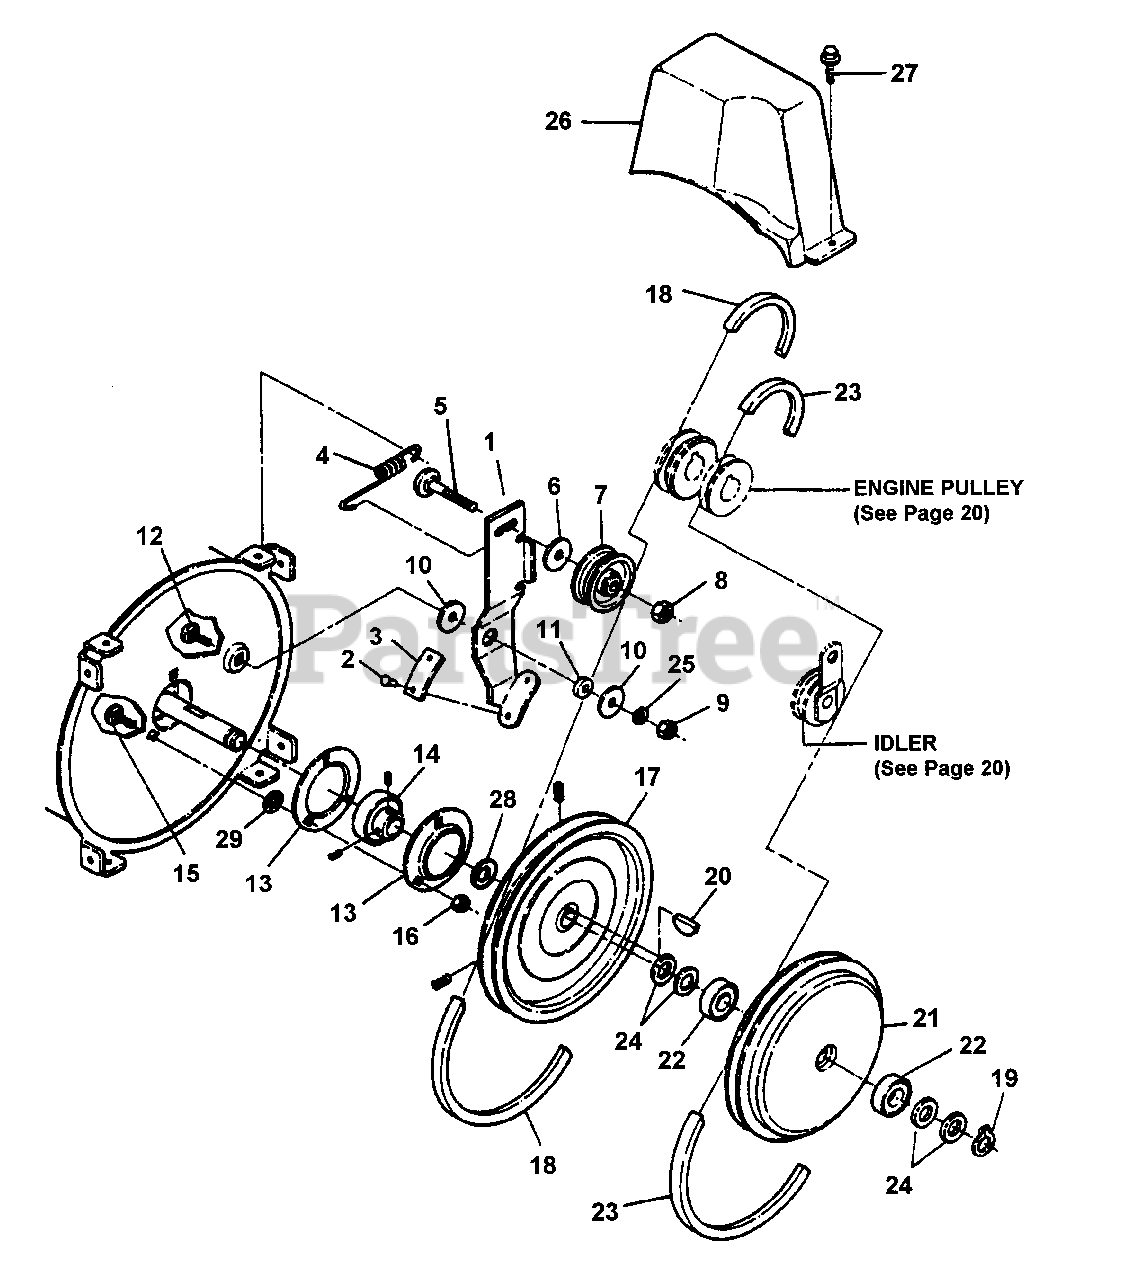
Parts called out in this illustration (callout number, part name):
1	ASSEMBLY, Idler Arm
2	RIVET
3	PAD, Brake
4	SPRING
5	BOLT, 3/8-16 x 1-1/2" Square Neck Carriage, Grade 2
6	WASHER, 3/8" Flat
7	PULLEY, Idler
8	NUT, 3/8-16 Hex Top Lock
9	NUT, 5/16-18 Hex, Grade B or 5
10	WASHER, 5/16 x 1-1/4" Flat
11	SPACER
12	BOLT, 5/16-18 x 1" Square Neck Carriage, Grade 5
13	HOUSING, Bearing
14	BEARING
15	BOLT, 5/16-18 x 3/4" Short Neck Carriage, Grade 5
16	NUT, 5/16-18 Hex Flange Lock, Grade 5
17	SHEAVE, Blower
18	BELT, Blower
19	RING, 1/2 External Snap (Heavy Duty)
20	KEY, 3/16 x 7/8" Woodruff
21	PLATE, Drive
22	BEARING, Ball
23	BELT, Traction
24	WASHER, 1/2 Shim
25	WASHER, 5/16 Split Lock
26	COVER, Belt Guard
27	SCREW, 1/4-20 x 1/2" Hex Washer Self-Tap
28	WASHER, 3/4 x 1-1/8" Flat
29	RETAINER, 5/16 Bolt
